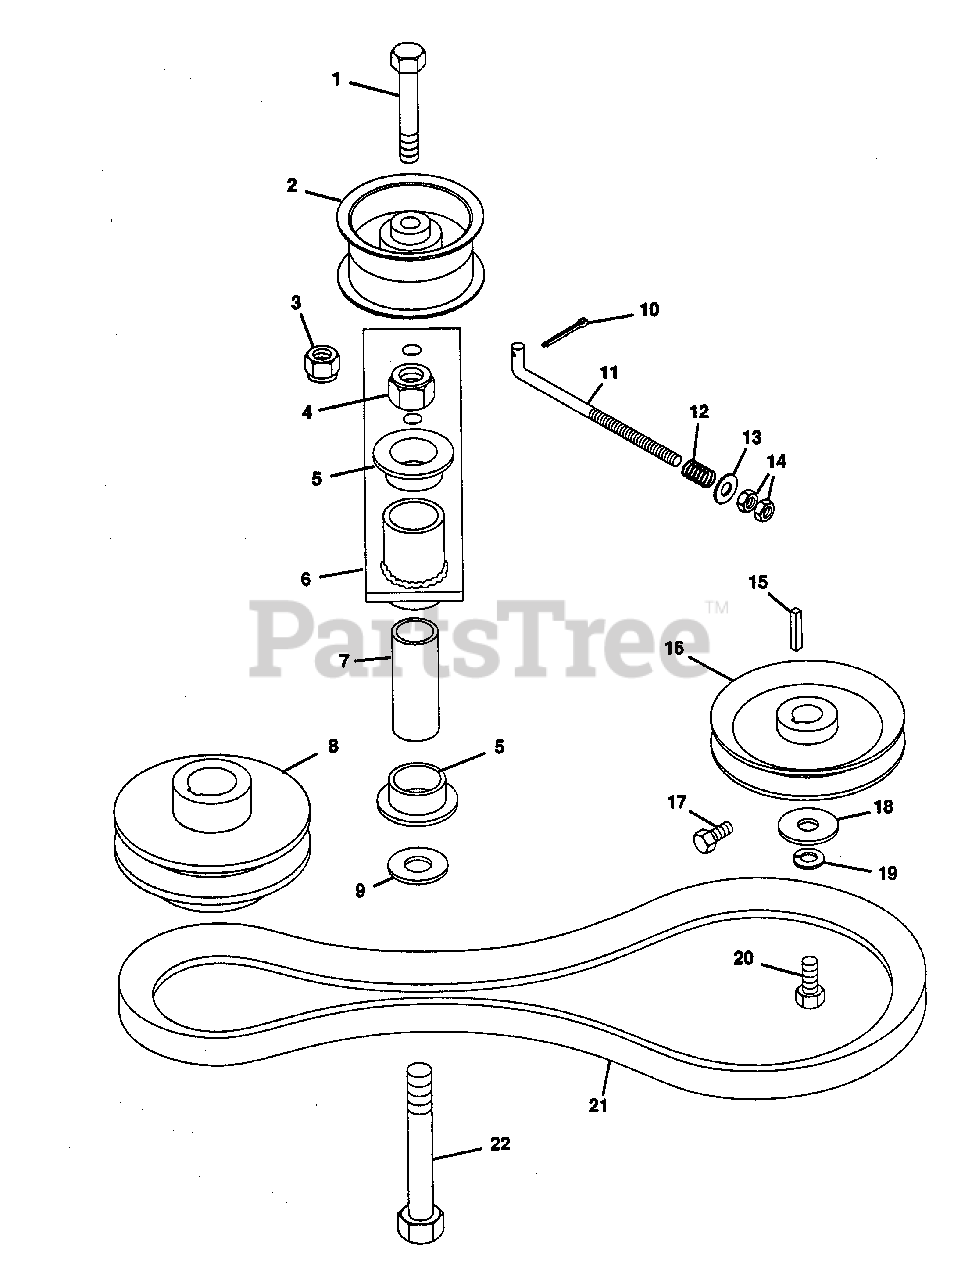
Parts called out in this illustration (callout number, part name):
1	Bolt, Hex 3/8-16x1.75
2	Pulley, Idler
3	Nut, Lock 3/8-16
4	Nut, Lock 112-13
5	Bush., Flg..764x1.47x.560 Ny.
6	Weldment, Ground Drive Idler
7	Bush., St..560x.745x2.04 St I.
8	Sheave, Engine Ground Drive
9	Washer, Flat .531x1 .062x.095
10	Pin, Cotter .094x.75
11	Rod, Idler
12	Spring, Comp. 1x.78x338 Lb/In
13	Washer, Flat .406x.812x.065
14	Nut, Hex 3/8-24
15	Key, 5mm Sq.x25mm Lg.
16	Sheave, Hydraulic Pump
17	Bolt, Hex 1/4-20x.50
18	Washer, Flat .265x1 .250x.063
19	Washer, Lock 1/4 Reg.
20	Bolt, Hex M6x1.Ox12mm Lg.
21	V-Belt, Engine to Pump
22	Bolt, Hex 1/2-13x3.00
